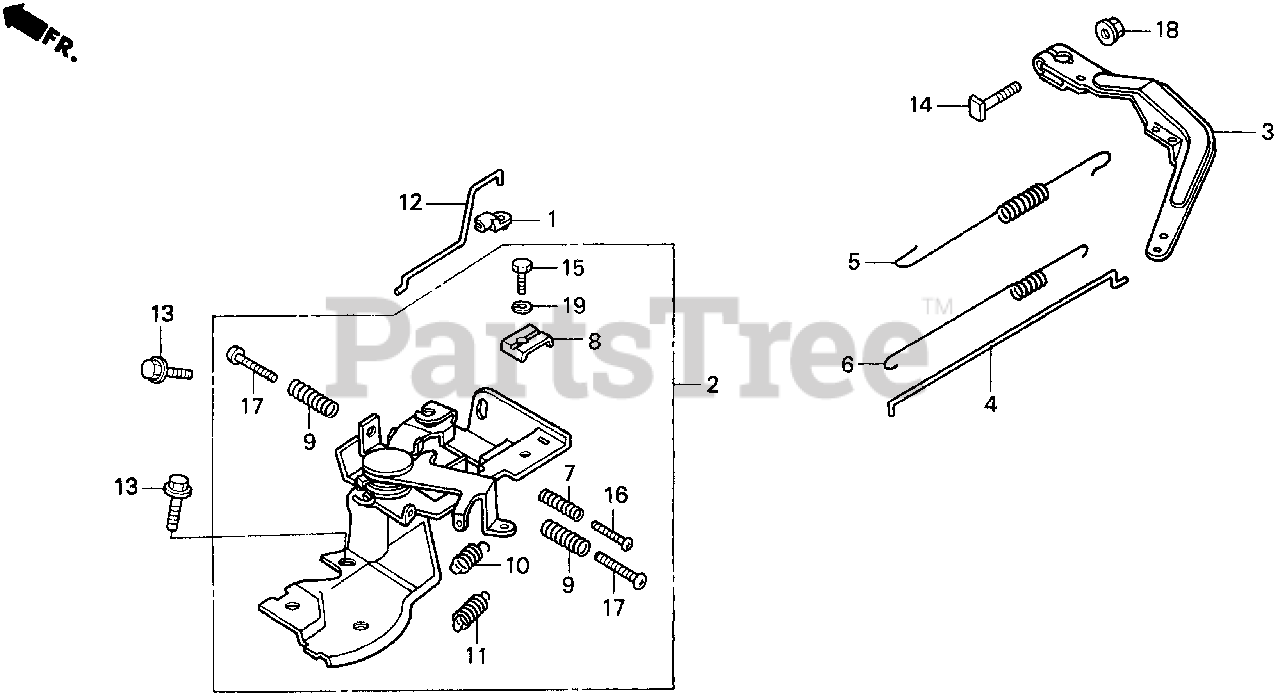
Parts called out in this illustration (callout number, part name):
1	JOINT, ROD
2	CONTROL ASSY.
3	ARM, GOVERNOR
4	ROD, GOVERNOR
5	SPRING, GOVERNOR
6	SPRING, THROTTLE RETURN
7	SPRING, CONTROL ADJUSTING
8	HOLDER, CABLE
9	SPRING, CONTROL ADJUSTING
10	SPRING, CABLE RETURN
11	SPRING, CABLE RETURN
12	ROD, CHOKE
13	BOLT, FLANGE (6X12) (CT200)
14	BOLT, GOVERNOR ARM
15	BOLT, RECESSED (5X16)
16	SCREW, PAN (4X20)
17	SCREW, PAN (5X20)
18	NUT, FLANGE (6MM)
19	WASHER, SPRING (5MM)
